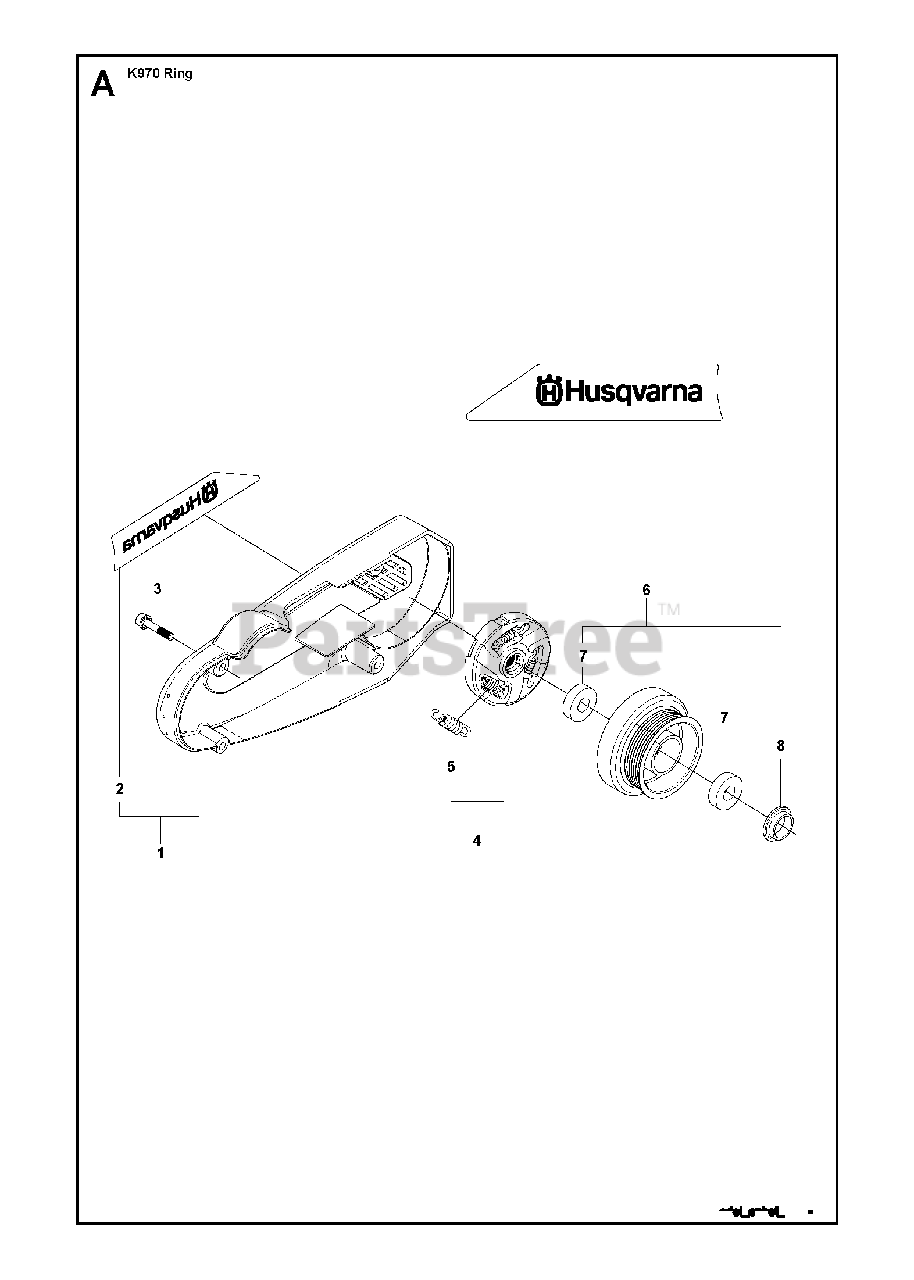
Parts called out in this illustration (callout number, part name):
3	SCREW ITXSCM
4	CLUTCH ASSYIncl. 5
5	CLUTCH SPRING
6	DRIVING PULLEY ASSYIncl 7 - 8
7	BALL BEARING
